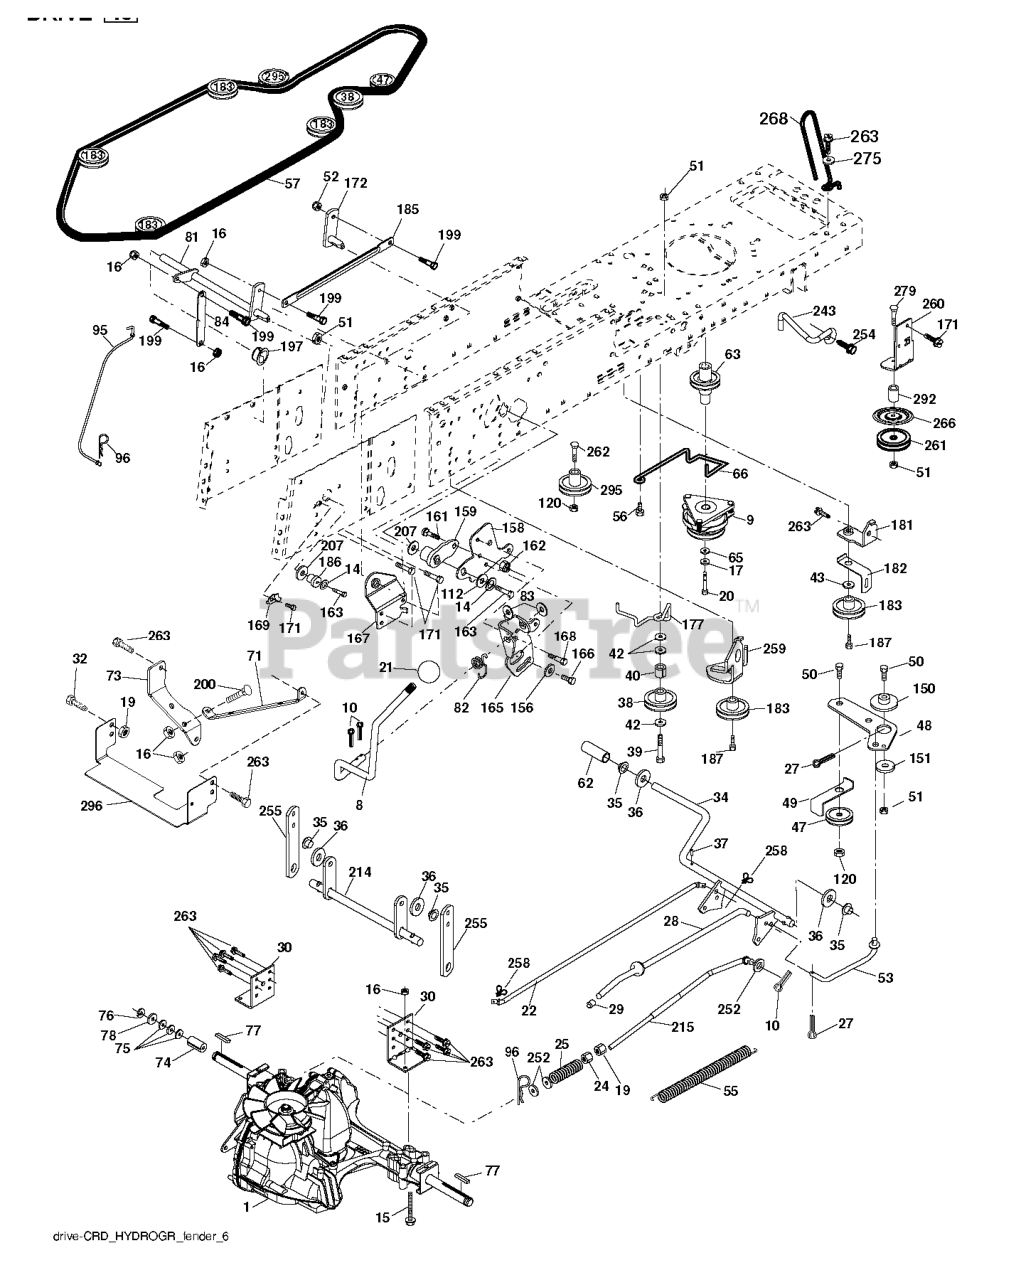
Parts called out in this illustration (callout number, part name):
8	ROD SHIFT FENDER ADJUST LT
9	CLUTCH.ELECTRIC.OGURA.EURO.
10	PIN COTTER
14	LOCKWASHER
15	BOLT HEX 5/16-18 GR 5
16	NUT.71038.31-18.HEX.NYLOCK
19	NUT
20	BOLT HEX 7/16-20X4-1/4"
21	KNOB.DUCKHEAD.1/2
22	ROD
24	NUT
25	SPRING BRAKE ROD
27	COTTER PIN
28	ROD, PARKING BRAKE
29	CAP
30	BRKT, TRNSXLE MNT 20"
32	BOLT
34	SHAFT, FOOT PEDAL
35	BEARING.NYLON
37	DRIVE PIN
38	PULLEY.FLAT
42	WASHER
47	IDLER PULLEY
48	BELLCRANK, CLUTCH
49	RETAIN BELT
50	BOLT.3/8-16X1.50
52	LOCKNUT
53	LINK.CLUTCH.7.66.2005
55	SPRING, RETURN LT
56	SCREW.3/8-16
57	V-BELT 113"
62	PEDAL COVER T
63	PULLEY.ENGINE.CVX.LT
65	LOCKWASHER
66	KEEPER BELT ENGINE
71	STRAP TORQUE RH HYDRO
73	STRAP TORQUE LH HYDRO
74	SPACER AXLE
77	SQUARE KEY
81	ASM.CROSS.SHAFT.REAR.CRD.0510
82	SHIFT SPRING
83	WASHER
84	LINK.PNT.TRANSAXLE.0510.CRD
95	LINK
96	RETAINER M
120	NUT LOCK FLG 3/8-16 UNC
150	BUSHING.BELLCRANK.GRD.DR
151	WASHER 12/32X2X10GA
156	WASHER.SRRTD.5/16
158	BRACKET
159	RB HUB.SHIFT
161	BOLT
162	NUT.CROWNLOCK.1/4
165	RP BRACKET
166	CAPSCREW.HXHD.FLG.5/16-18X.625
167	BRACKET.SUPT.SHIFT.CRD
168	BOLT.SHOULDER.5/16-18X
169	PLATE.FASTENING.CROSS.SHAFT
172	LINK
181	BRACKET
182	BELT GUIDE
183	PULLEY.V-IDLER.GRND.DR
185	LINK
186	HUB.TAPERED.ROUND.CRD
187	BOLT.5/16-18X1.25
197	NYLINER SNAP 5/8" ID
199	BOLT SHOULDER 5/16-18 UNC
207	WASHER NYL
214	LEVER
215	ROD
243	BRACKET, ANTI-ROTATION
252	WASHER
254	SCREW 3/8-16X1
255	SHAFT
258	CLIP RETAINER
259	BRACKET
261	FLAT IDLER PULLEY
263	SCREW, 3/8-16X3/4
266	PROTECTOR
268	GUARD MUFFLER
275	WASHER
292	SPACER
295	PULLEY IDLER COMPOSITE
